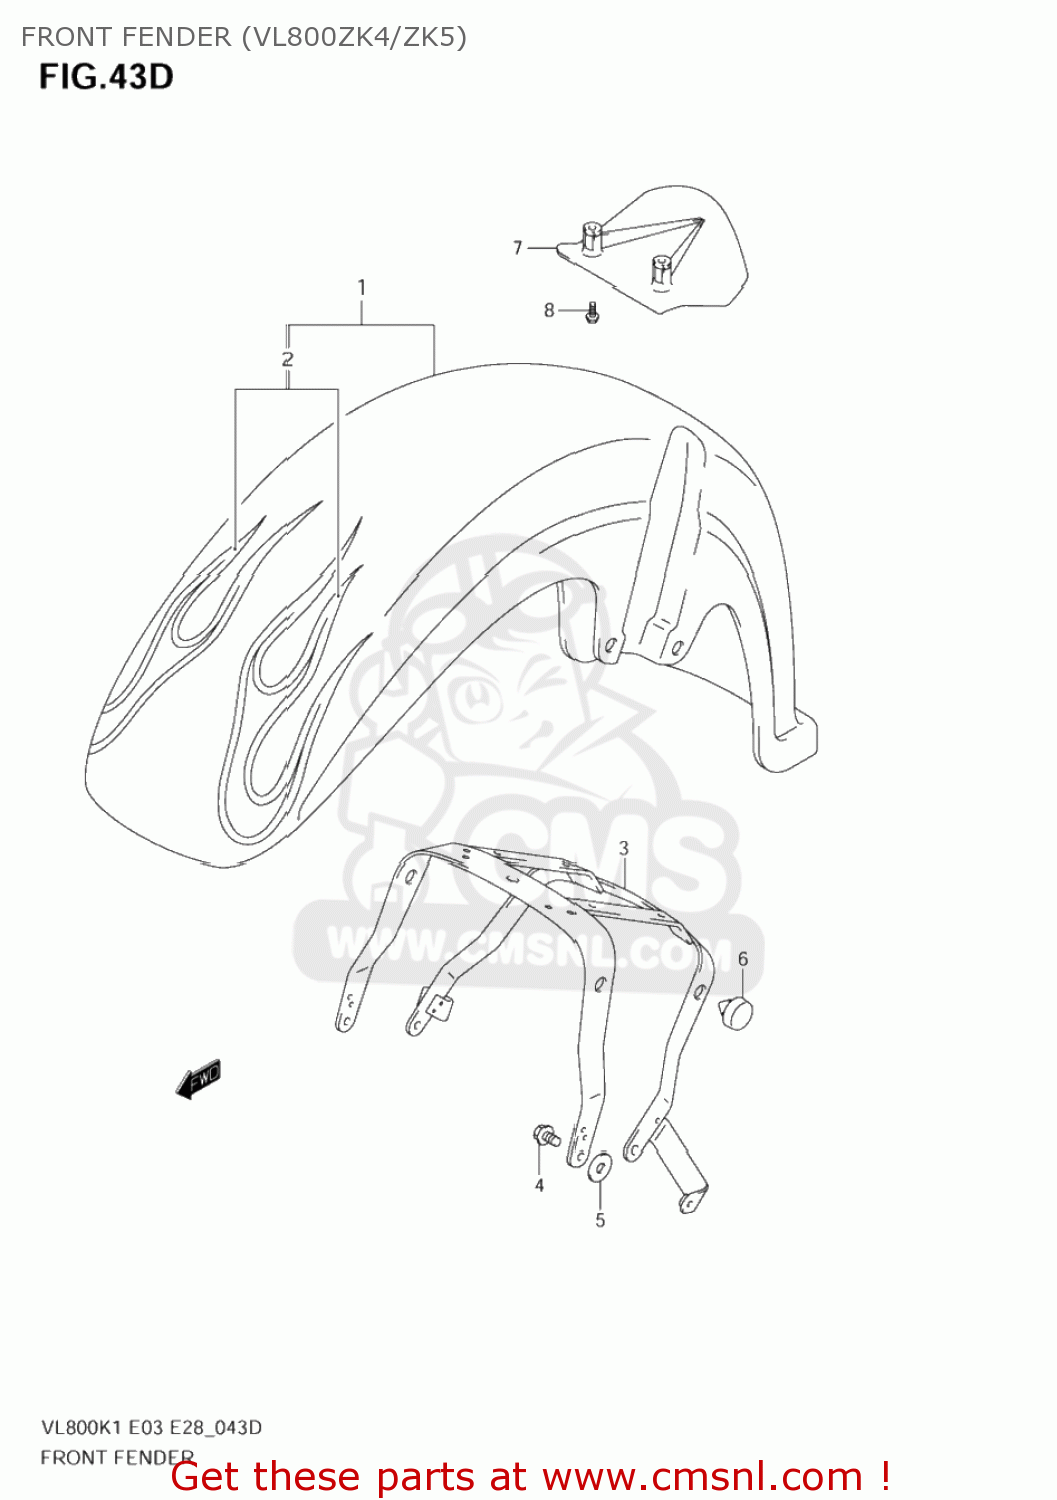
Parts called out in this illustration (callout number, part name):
1	FENDER,FR
2	TAPE SET,FR FENDER
3	BRACE,FR FENDER
4	BOLT
5	WASHER,FR FENDER
6	CUSHION
7	WING,FR
8	BOLT(6X16)
